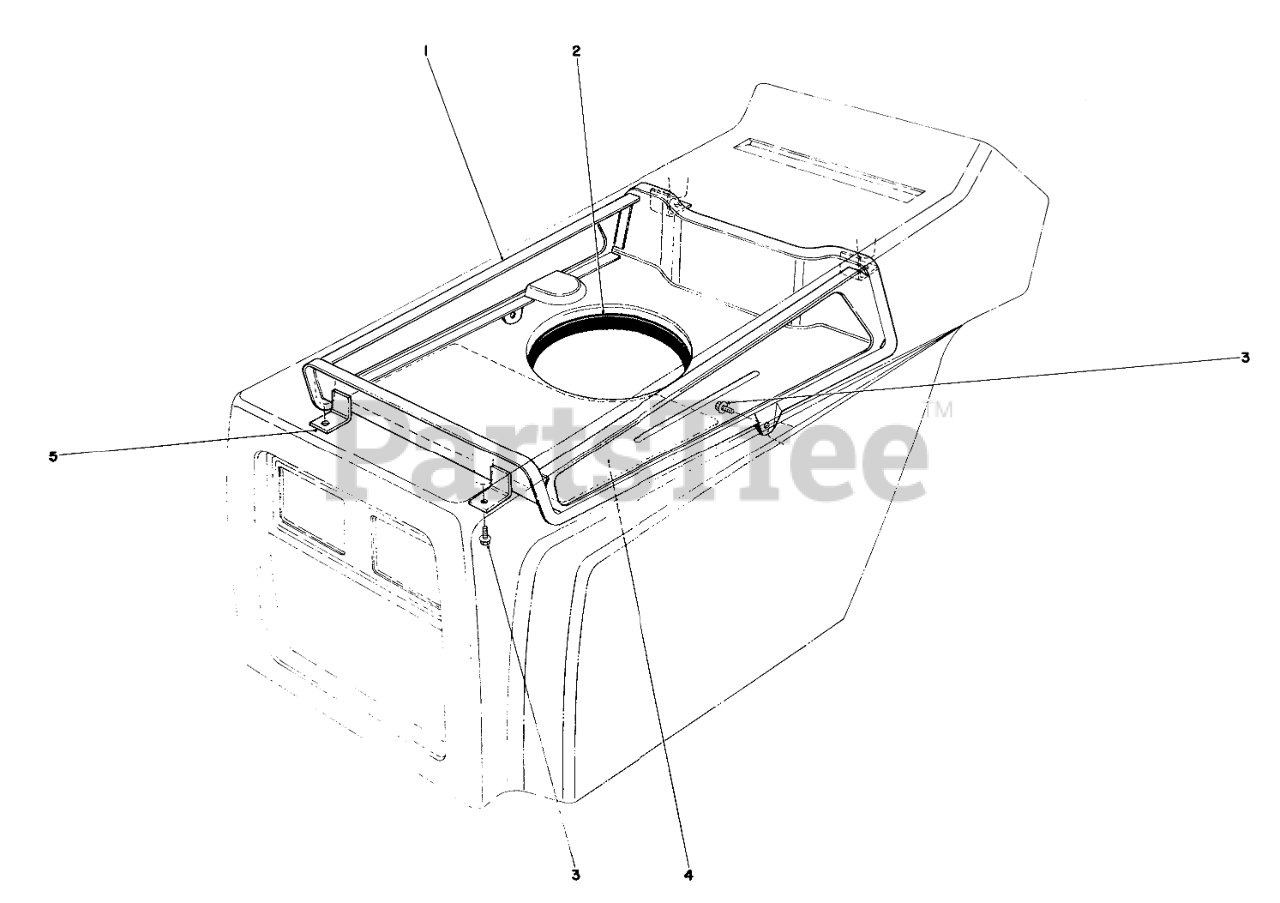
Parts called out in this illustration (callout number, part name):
1	Duct Hood
2	Seal Engine
3	SCREW-HWHTF
4	Decal Service
5	Bracket Duct Support
